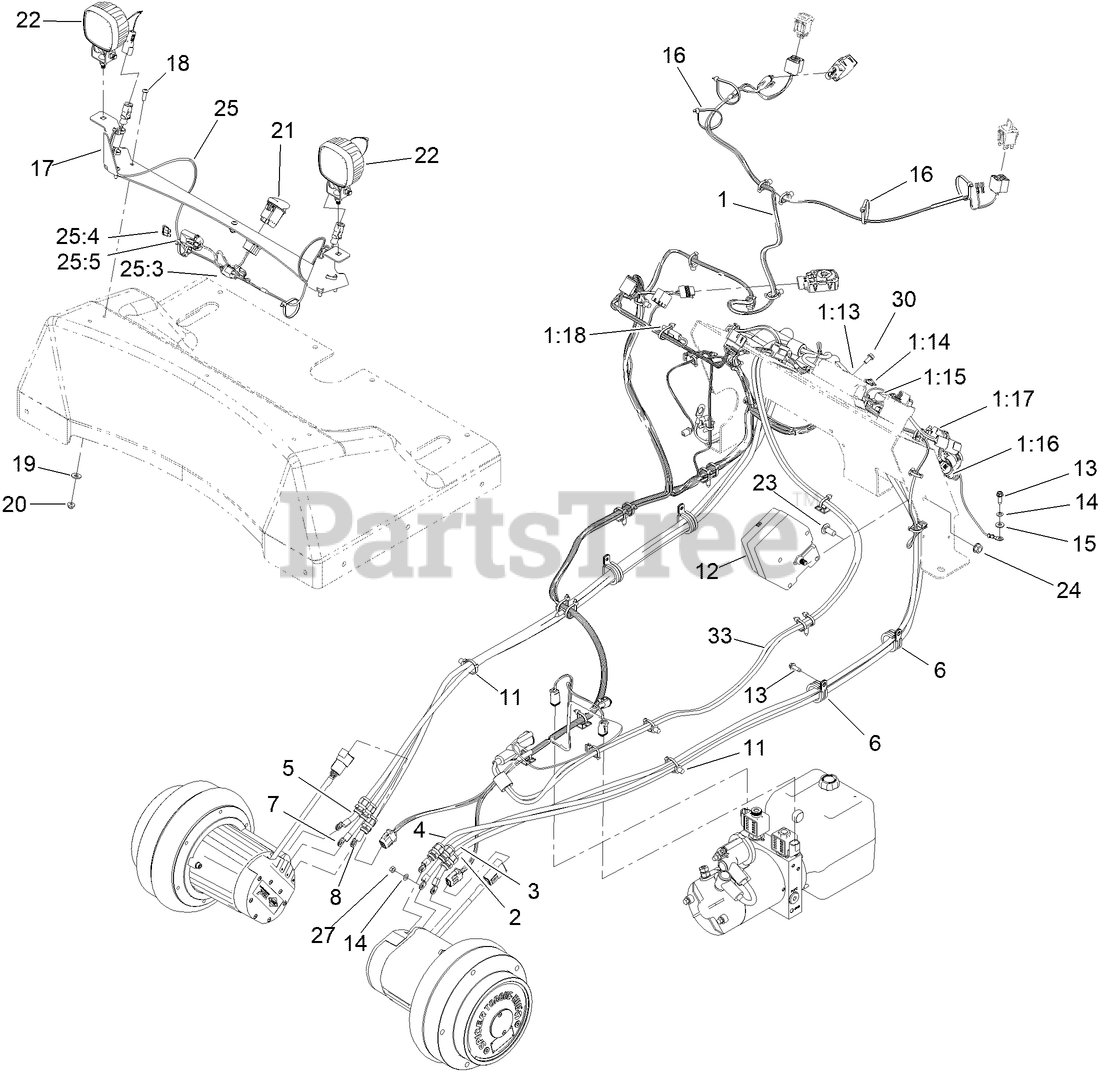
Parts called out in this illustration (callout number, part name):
1	HARNESS-WIRE, MAIN
1:13	FUSE-BLADE, 5A
1:14	FUSE-BLADE, 10A
1:15	COVER-APTIV, MODIFIED
1:16	RESISTOR-120 OHM
1:17	CAP-PLUG, 3 WAY
1:18	CAP-PLUG
2	CABLE-BATTERY, RD ASM
3	CABLE-BATTERY, RD ASM
4	CABLE-BATTERY, RD ASM
5	CABLE-BATTERY, RD ASM
6	R-CLAMP
7	CABLE-BATTERY, RD ASM
8	CABLE-BATTERY, RD ASM
11	CLIP-TIE
13	SCREW-HWHTF
14	WASHER-SPRING
15	WASHER-FLAT
16	TIE-CABLE
17	BRACKET-MOUNT,LIGHT [BLACK]
18	SCREW-HSBH
19	WASHER-FLAT
20	NUT-HF
21	SWITCH
22	LIGHT-WORK
23	SCREW-CARR
24	NUT-HHF, WHIZ
25	HARNESS-WIRE, LIGHT KIT
25:3	CAP-DUST, 2 WAY
25:4	FUSE-BLADE, 3A
25:5	COVER-APTIV, MODIFIED
27	NUT-HEX
30	SCREW-SEMS
33	CABLE-BATTERY, RD AND BK ASM
